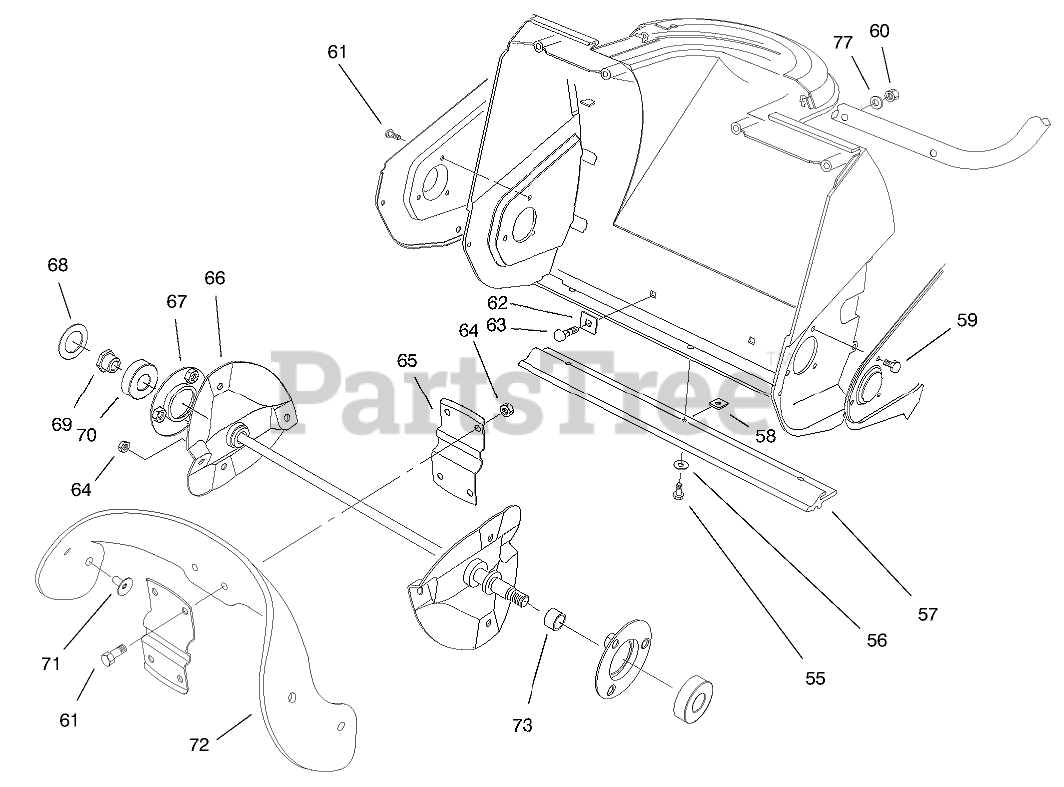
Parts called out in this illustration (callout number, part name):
55	SCREW-HWHTF
56	WASHER-FLAT
57	SCRAPER
58	NUT-CLIP, U
59	SCREW-HH
60	NUT-LOCK, NI
61	SCREW-HHF
62	WASHER-SQUARE
63	SCREW-CARR
64	NUT-LOCK, NI
65	Support-Rotor
66	Rotor
67	FLANGE BEARING ASM
68	WASHER-RUBBER
70	BEARING-BALL
71	SCREW
72	BLADE-ROTOR
73	SPACER
77	WASHER
